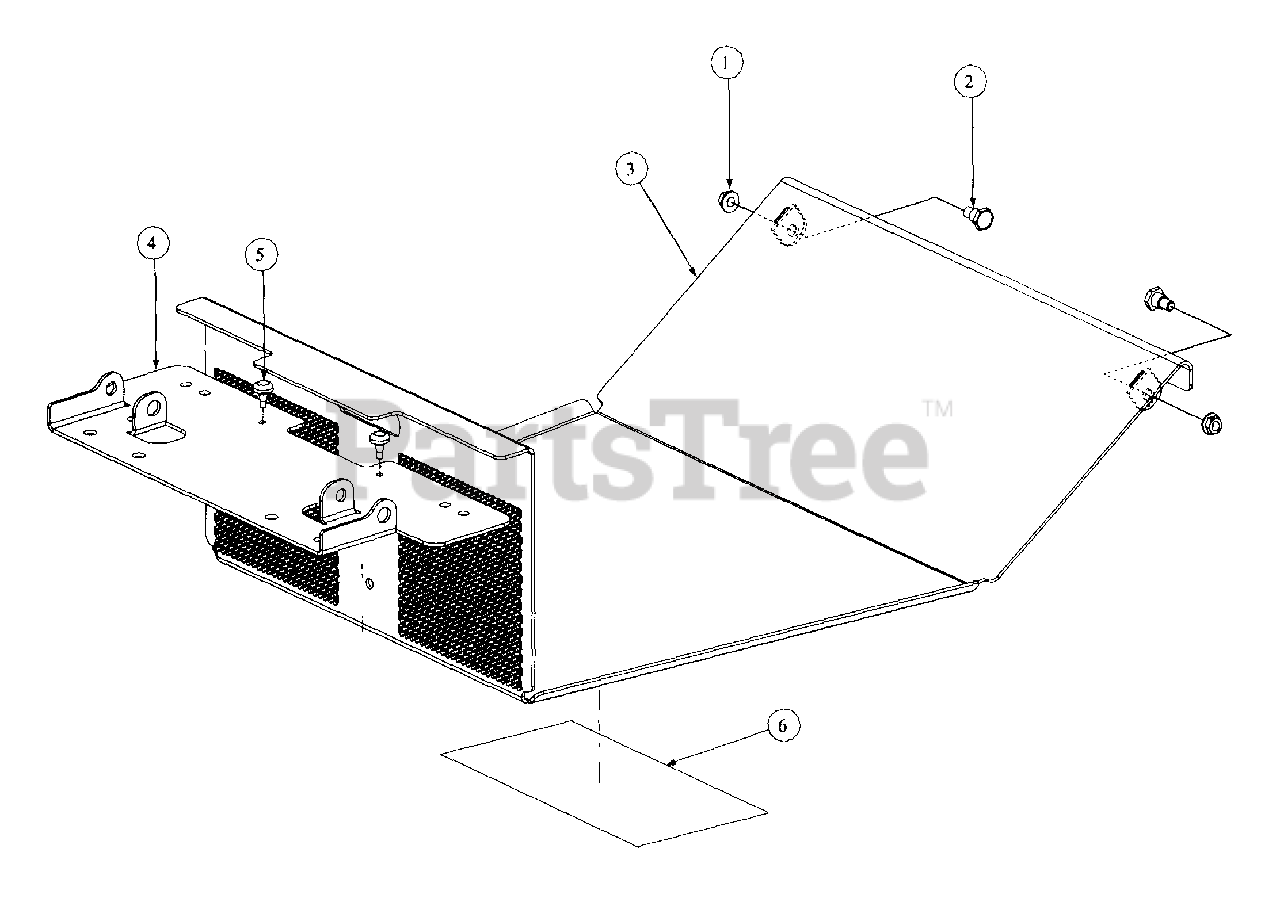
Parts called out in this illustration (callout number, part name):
1	Lock Nut, Hex Flange 5/16-18
2	Shoulder Screw, .435 x .350, 5/16-18
3	Floor Assembly Panel
4	Panel Seat
5	Rubber Bumper, .62 OD x .22 THK
6	Label, Belt Routing E Lubrication
